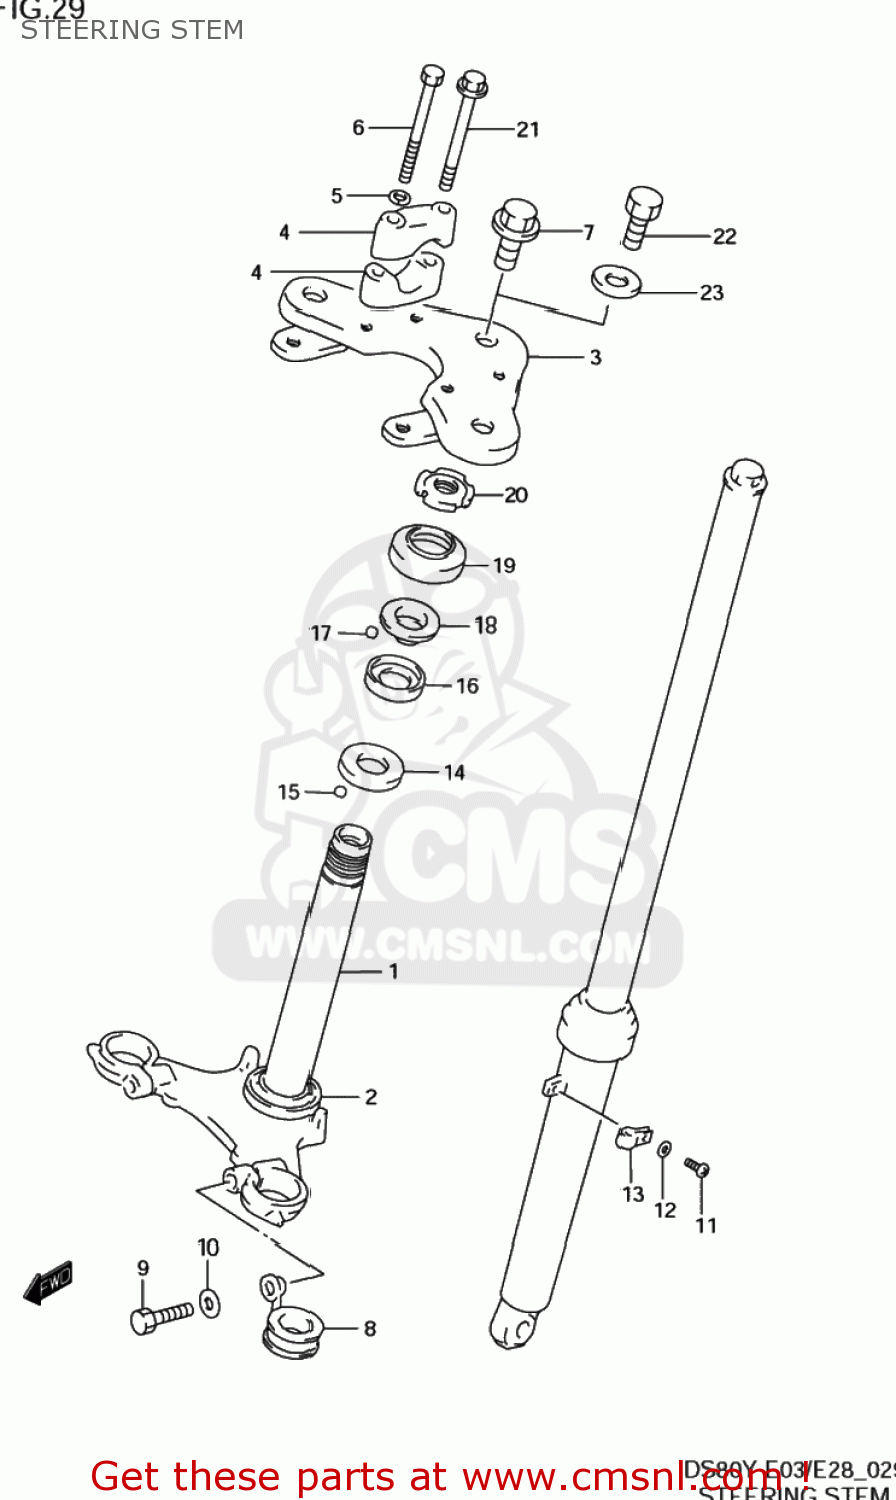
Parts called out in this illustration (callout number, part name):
1	STEM,STEERING
2	RACE,STEERING OUTER LWR
3	HEAD,STEERING STEM
4	HOLDER,HANDLE UPR
5	WASHER
6	BOLT
7	BOLT
8	CLIP
9	BOLT
10	WASHER,LOCK
11	SCREW
12	WASHER,LOCK
13	CLIP,FR BRAKE CABLE
14	LACE,STEERING INNER LWR
15	BALL
16	RACE,STEERING INNER UPR
17	BALL
18	RACE,STEERING OUTER UPR
19	DUST SEAL,STEERING UPR
20	NUT,STEERING STEM(25X44X10)
21	BOLT
22	BOLT
23	WASHER(10.5X30X2.3)
